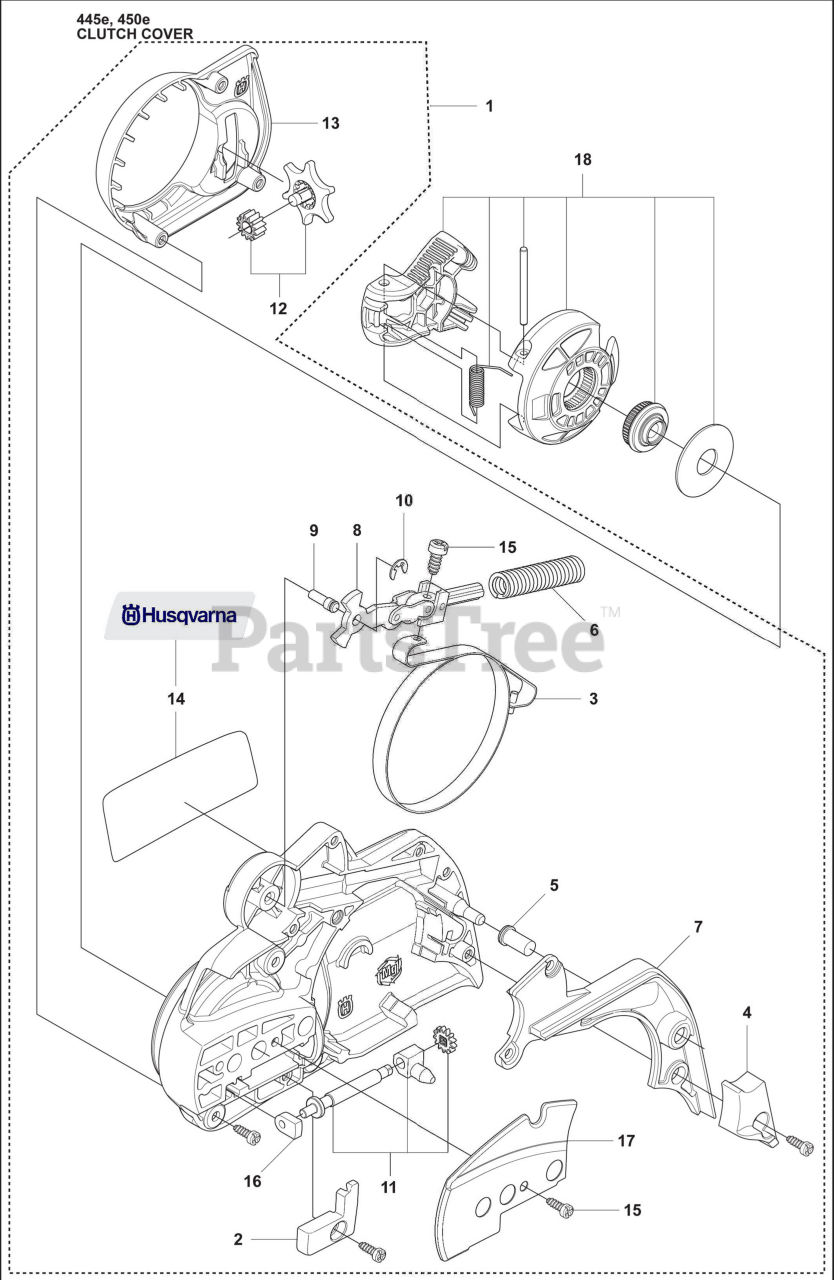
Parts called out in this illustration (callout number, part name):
1	Clutch Housing, Complete
2	Cover
3	Brake Band
4	Chain Wear Guard
7	Chain Brake Cover
10	Bar Retainer
11	Chain Tensioner Screw, Comp
12	Chain Tensioner Wheel
13	Heat Shield
14	Clutch Housing Decal
16	Sleeve Bearing
18	Complete Knob
